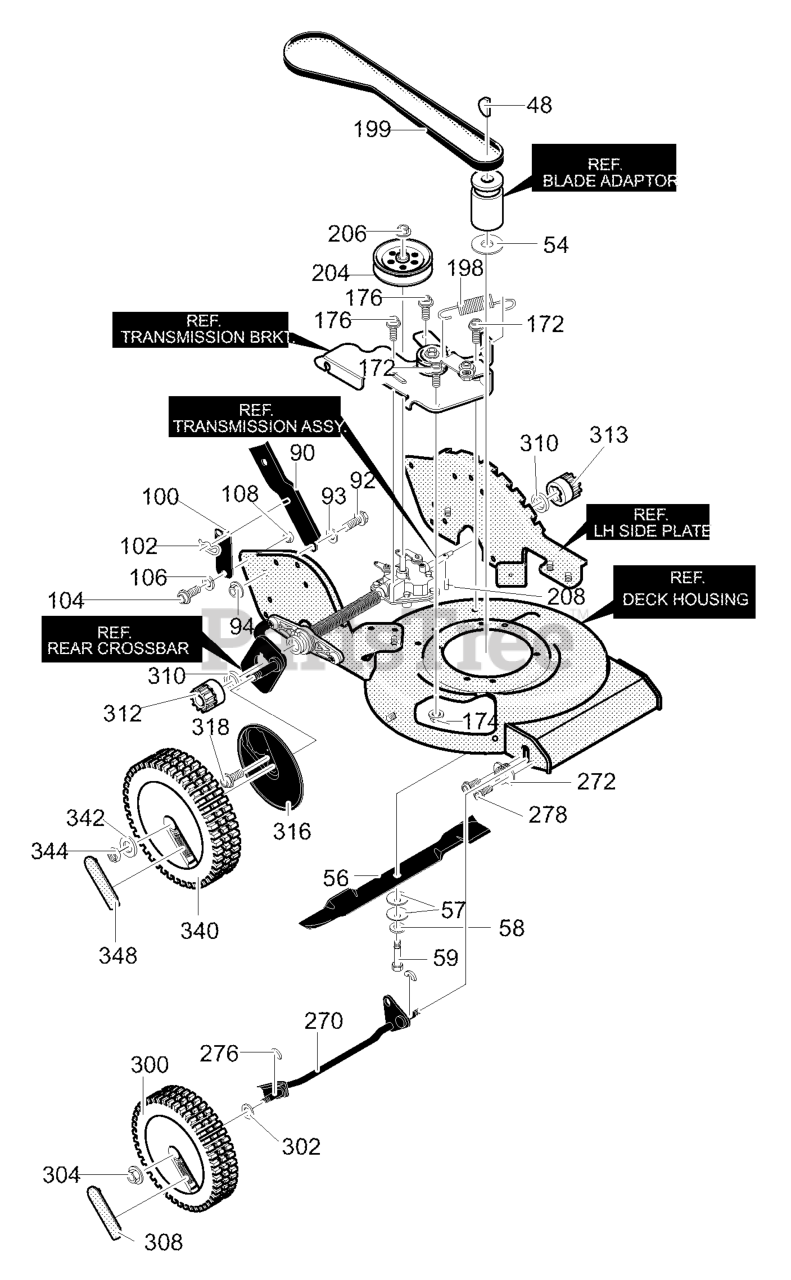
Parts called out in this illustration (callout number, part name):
48	Key, Woodruff
54	Spacer, Blade Adapter
56	Blade, 22" Mulch
57	Washer
58	Flatwasher
59	Screw, 3/8-24 x 2.00
90	Bracket, Assy. Handle
92	Bolt, HHSH 3/8-16
93	Washer, Spring
94	Nut, 3/8-16
100	Strap, Handle Adj.
102	Hair Pin
104	Bolt, HHSH 3/8-16
106	Washer, Spring
108	Nut, 3/8-16
172	Bolt, HHSH 3/8-16
174	Nut, 3/8-16
198	Tension Spring
199	Belt, V3L
204	Engine Pulley
206	Nut, Hnyl
208	Drive Pin
270	Crossbar, Assy. Front
272	Clip, Front Axle
276	Bushing, Front Hsing
278	Screw, 1/4-20x.63
300	Tire & Rim
302	Washer, Spring
304	Nut, 3/8-16
308	Hubcap
310	Flatwasher
312	Gear, Pinion RH
313	Gear, Pinion LH
316	Dustcover, 8" Wheel
318	Screw, 1/4-20x.50
340	Wheel, Drive
342	Flatwasher
344	Nut, 3/8-16
348	Hubcap, 8" Wheel
